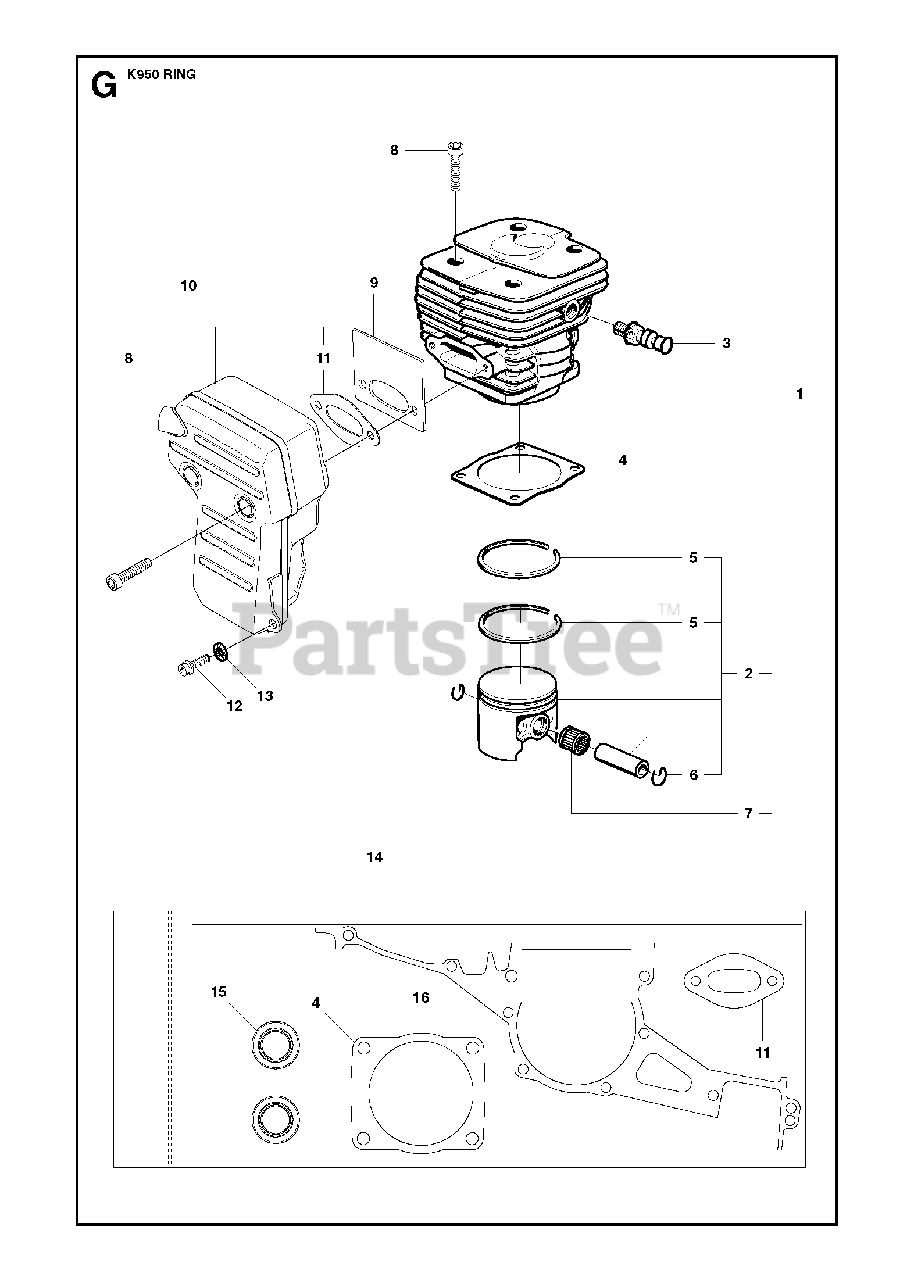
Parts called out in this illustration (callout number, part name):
1	CYLINDER ASSYIncl. 2, 7
2	PISTON ASSYIncl. 5, 6
3	DECOMPRESSION VALVE
4	CYLINDER BASE GASKETGasket kit 15
7	NEEDLE BEARING
9	COOLING PLATE
10	MUFFLER ASSYIncl. 8, 11
11	GASKETGasket kit 15
12	SCREW IHSCFM
14	GASKET KITIncl. 4, 12, 15, 16
15	SEALING RING
